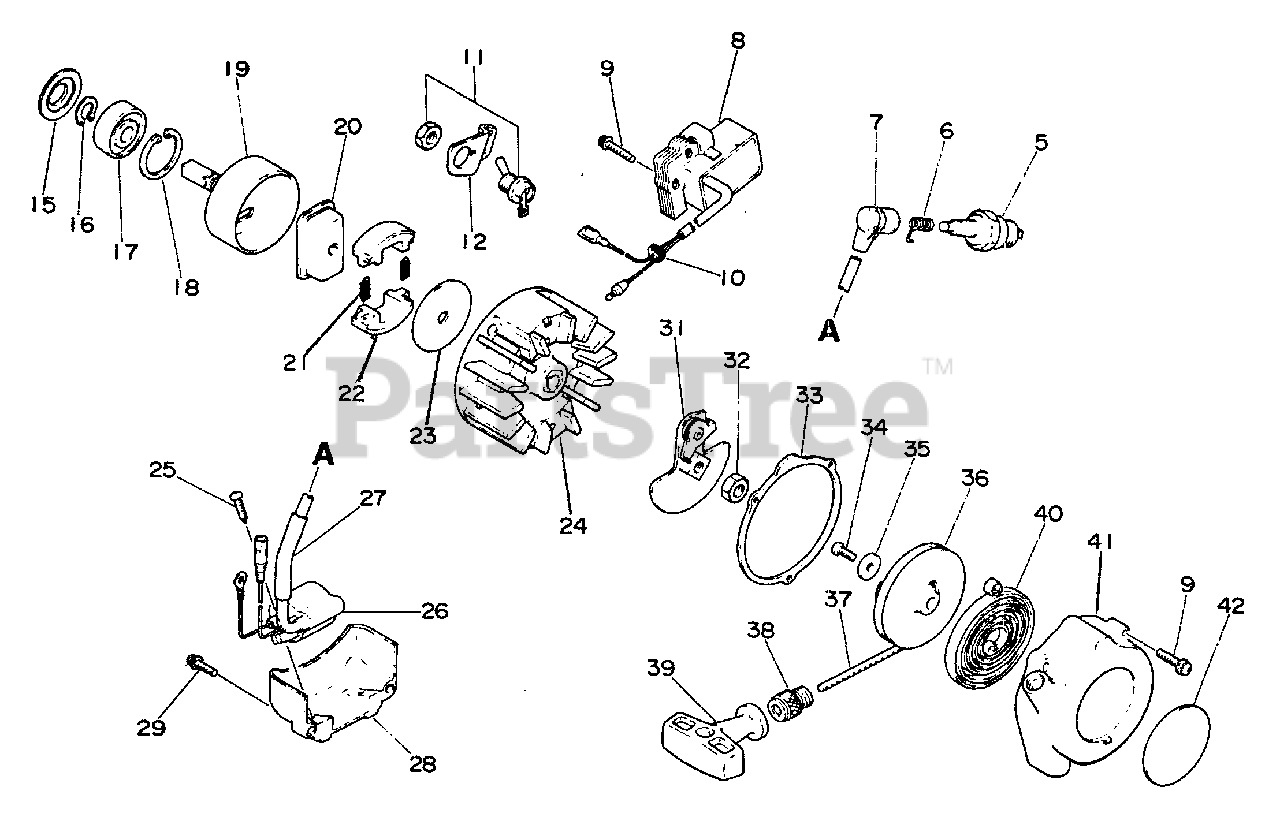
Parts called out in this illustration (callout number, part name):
5	SPARK PLUG -- CJ-8
6	TERMINAL, SPARK PLUG CAP
7	CAP, SPARK PLUG
8	COIL, IGNITION
9	SCREW - 4X20
11	IGNITION SWITCH KIT
12	BRACKET, SWITCH
15	RETAINER, PIPE
16	RING, RETAINING - 12
17	BEARING, BALL - 6201
18	RING, RETAINING - 32
19	DRUM, CLUTCH
20	HUB, CLUTCH
21	SPRING, CLUTCH
22	SHOE, CLUTCH
23	PLATE, CLUTCH
24	FLYWHEEL
25	SCREW - 4X16 -- TAPPING
26	COIL, IGNITION
27	TUBE
28	COVER
29	SCREW - 4X14
31	STARTER PAWL ASSY
33	GASKET, STARTER
34	SCREW - 4X10
36	REEL, ROPE
37	ROPE, STARTER - 3X850
38	GUIDE, ROPE
39	GRIP, STARTER
40	SPRING, REWIND
41	CASE, STARTER
42	LABEL - ECHO
